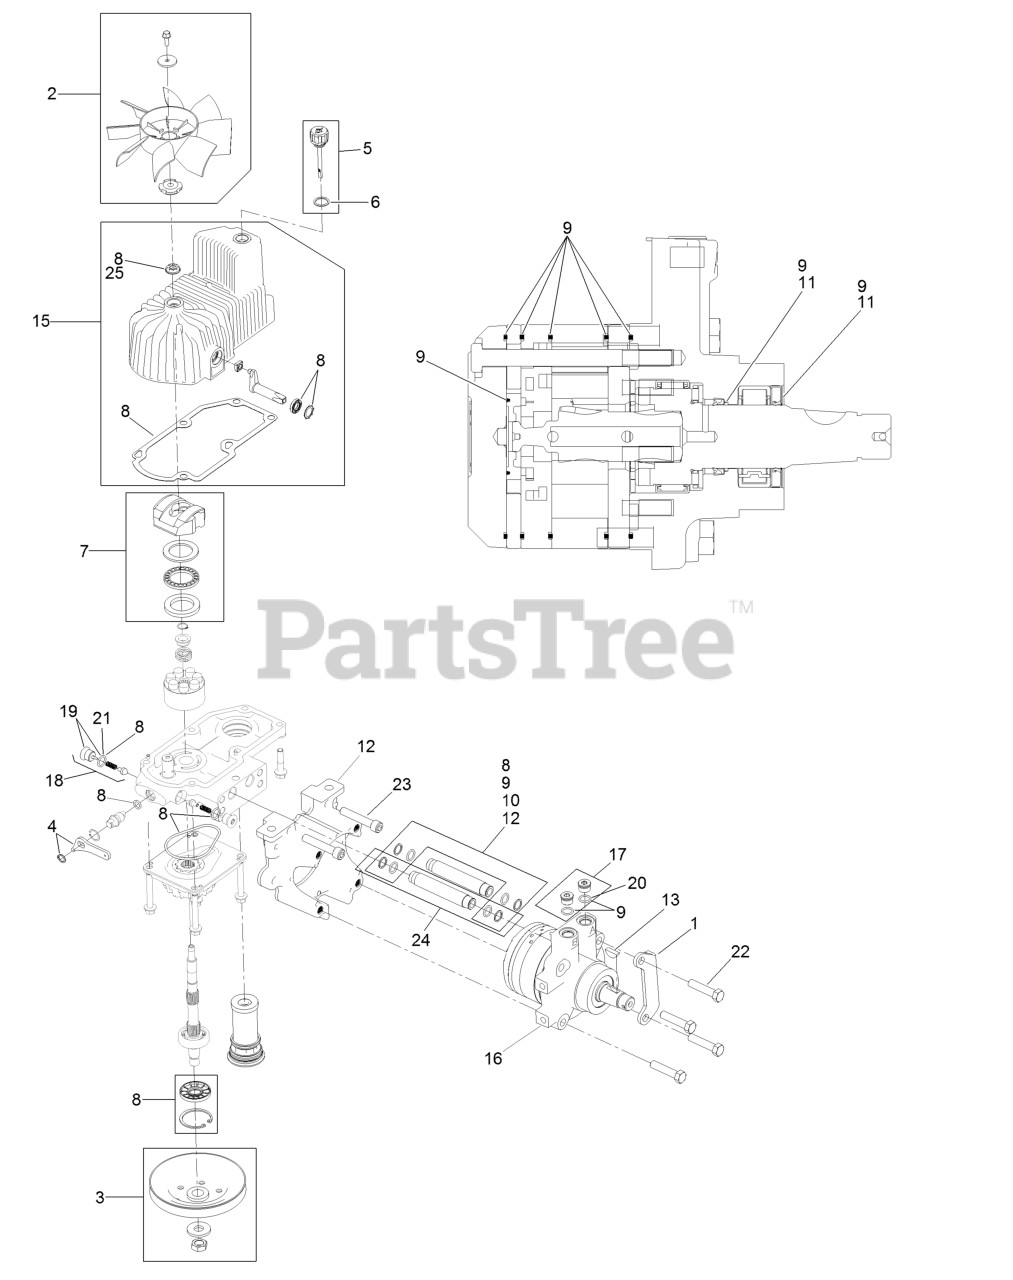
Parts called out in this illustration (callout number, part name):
1	Mount-Shoe, Horse
2	Fan Kit
3	Pulley Kit
4	Handle-Bypass Valve, Hydro
5	Dipstick-Hydro W/Gasket
6	Gasket-Dipstick, Hydro
7	Swash Block Kit
8	Pump Seal Kit
9	Motor Seal Kit
10	Tube Seal Kit
11	Output Shaft Seal Kit
12	Nose Cup-Uht
13	Key-Woodruff
15	Housing-RH
16	Motor-Hydraulic RH 240Cc
17	Magnetic Plugs Service Kit
18	Check Valve ASM
19	Plug-Check (W/O-Ring)
21	O-Ring-Check Valve
22	Screw HH
23	Screw-HSH
24	Hydraulic Tube Kit
25	Seal-Fan Drive
99	Flow Test Kit
99	Puller-Pulley
